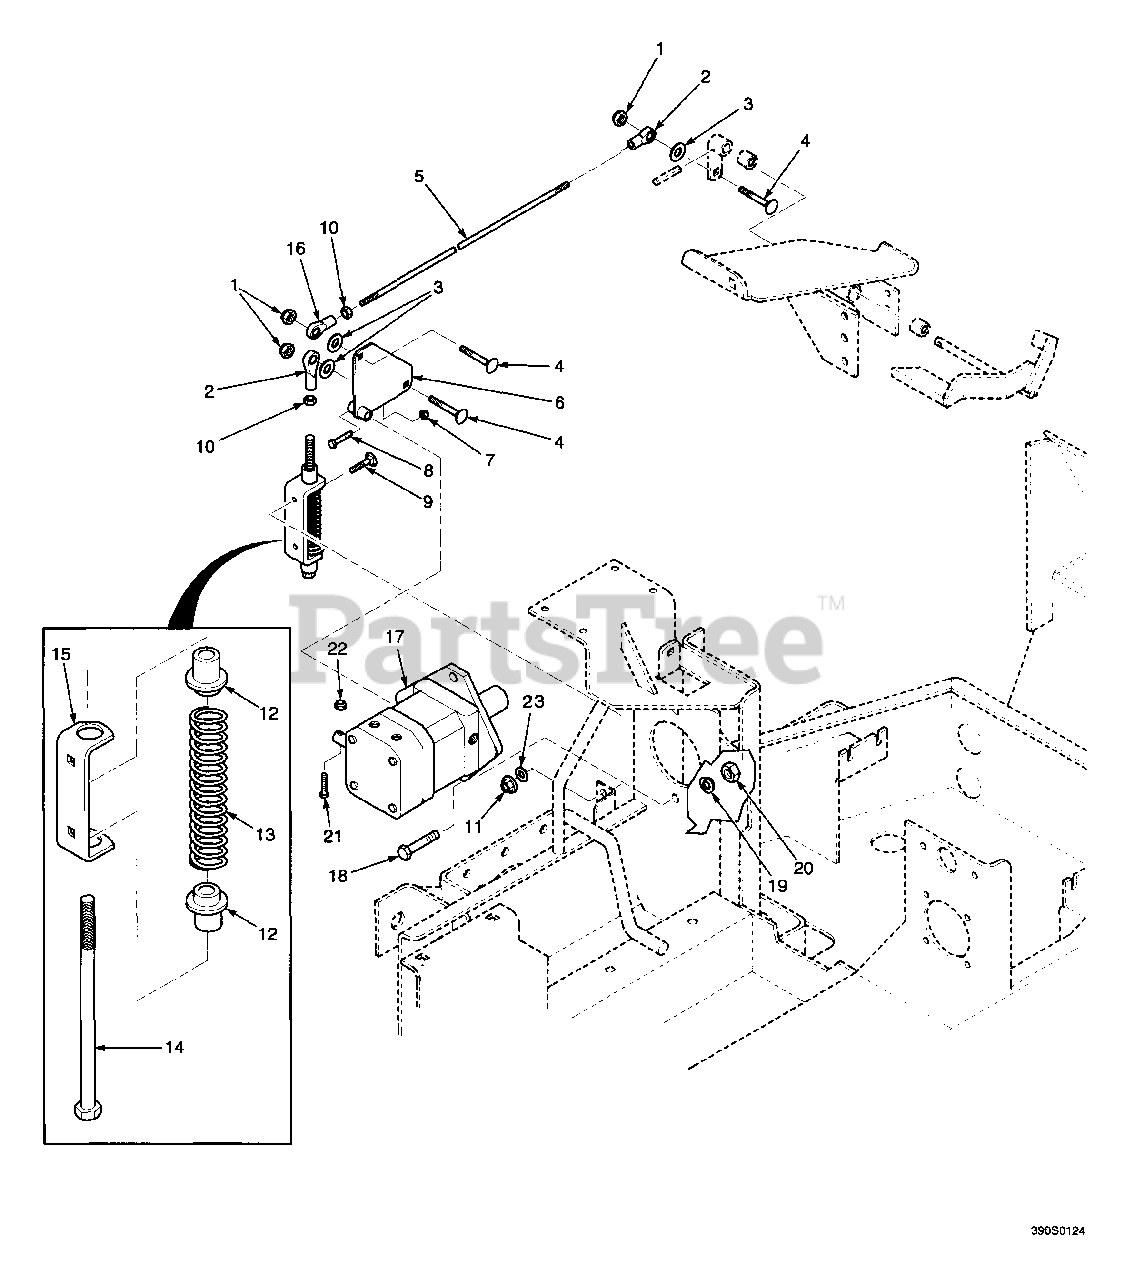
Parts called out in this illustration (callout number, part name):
1	Hex Locknut, Elastic Stop, 3/8-16
2	Ball Joint, 3/8-24 LH Thread
3	Flatwasher, 3/8 (.391 x .938 x .105)
4	Carriage Bolt, 3/8-16 x 1-1/2
5	Rod, Transmission Control
6	Bellcrank, Pump Control
7	Hex Locknut, Elastic Stop, 1/4-20
8	Bolt, Hex Head, 1/4-20 x 1-1/4
9	Carriage Bolt, 5/16-18 x 1
10	Hex Nut, 3/8-24
11	Serr. Fl. Hex Nut, 5/16-18
12	Bushing, Spring Keeper
13	Spring, Neutral Return
14	Bolt, Neutral Adjustment, 3/8-24 x 6-3/4
15	Retainer, Neutral Spring
16	Ball Joint, 3/8-24 RH Thread
17	Hydraulic Pump
18	Bolt, Hex Head, 1/2-13 x 1-1/2
19	Lockwasher, 1/2
20	Hex Nut, 1/2-13
21	Screw, Round Head, #10-32
22	Hex Nut, Elastic Stop, #10-32
23	Flatwasher, 5/16 (.375 x.875 x .083)
